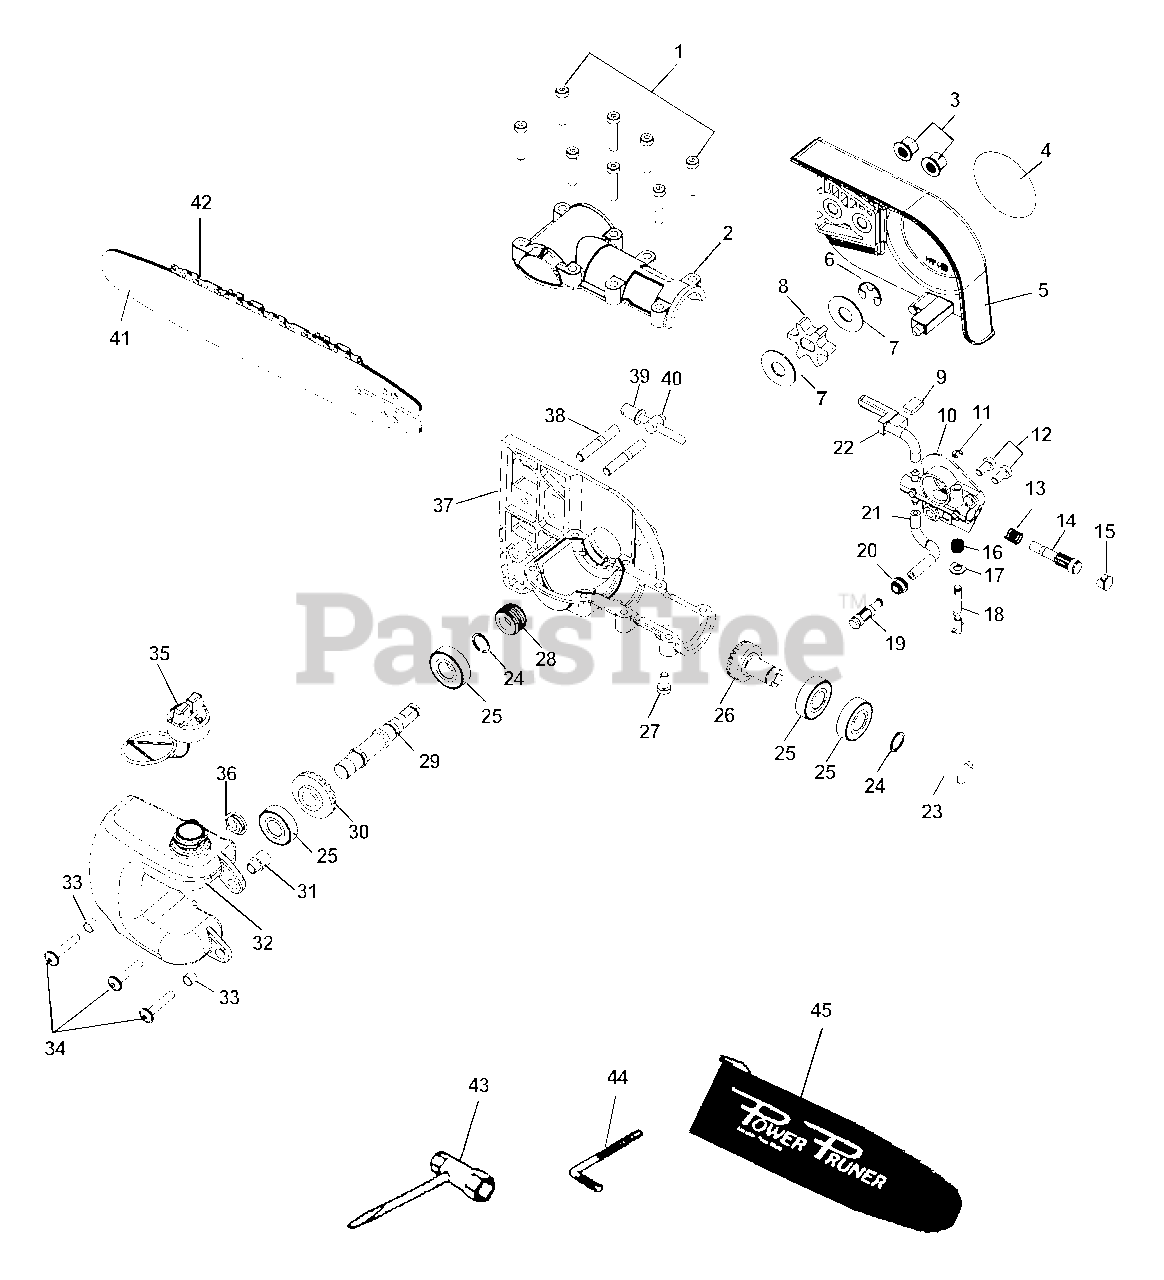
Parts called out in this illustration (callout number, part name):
1	SCREW - 5X25
2	CASE, GEAR - UPPER
3	NUT - 6 -- FLANGE
4	LABEL - ECHO
5	GUARD, SPROCKET
6	RING, RETAINING
8	SPROCKET, DRIVE
9	PAD, FOAM
10	AUTO-OILER ASSY
11	RING, RETAINING
12	SCREW - 5X10
13	SPRING, PLUNGER
14	PLUNGER ASSY
15	CAP, OIL PUMP
18	NEEDLE, ADJUST
19	FILTER, OIL
20	GROMMET
21	PIPE - 3X6X75 -- BLACK
22	PIPE, OIL OUTLET
23	COLLAR - 22
24	RING, RETAINING - 12
25	BEARING, BALL - 6001
26	GEAR - BEVEL
27	SCREW - 5X10
28	GEAR - WORM
29	GEAR - SHAFT
30	GEAR - BEVEL
32	TANK, OIL
34	SCREW - 5X20
35	CAP ASSY
37	CASE, GEAR - LOWER
38	STUD - 6
39	SCREW, TENSIONER
40	TENSIONER, CHAIN
41	GUIDE BAR - 12" (30cm)
41	GUIDE BAR - 12" (30cm) Intenz
42	SAW CHAIN - 12" (30cm)
43	T-WRENCH
44	HEX KEY - 3mm
45	COVER, GUIDE BAR - 12" (30cm)
